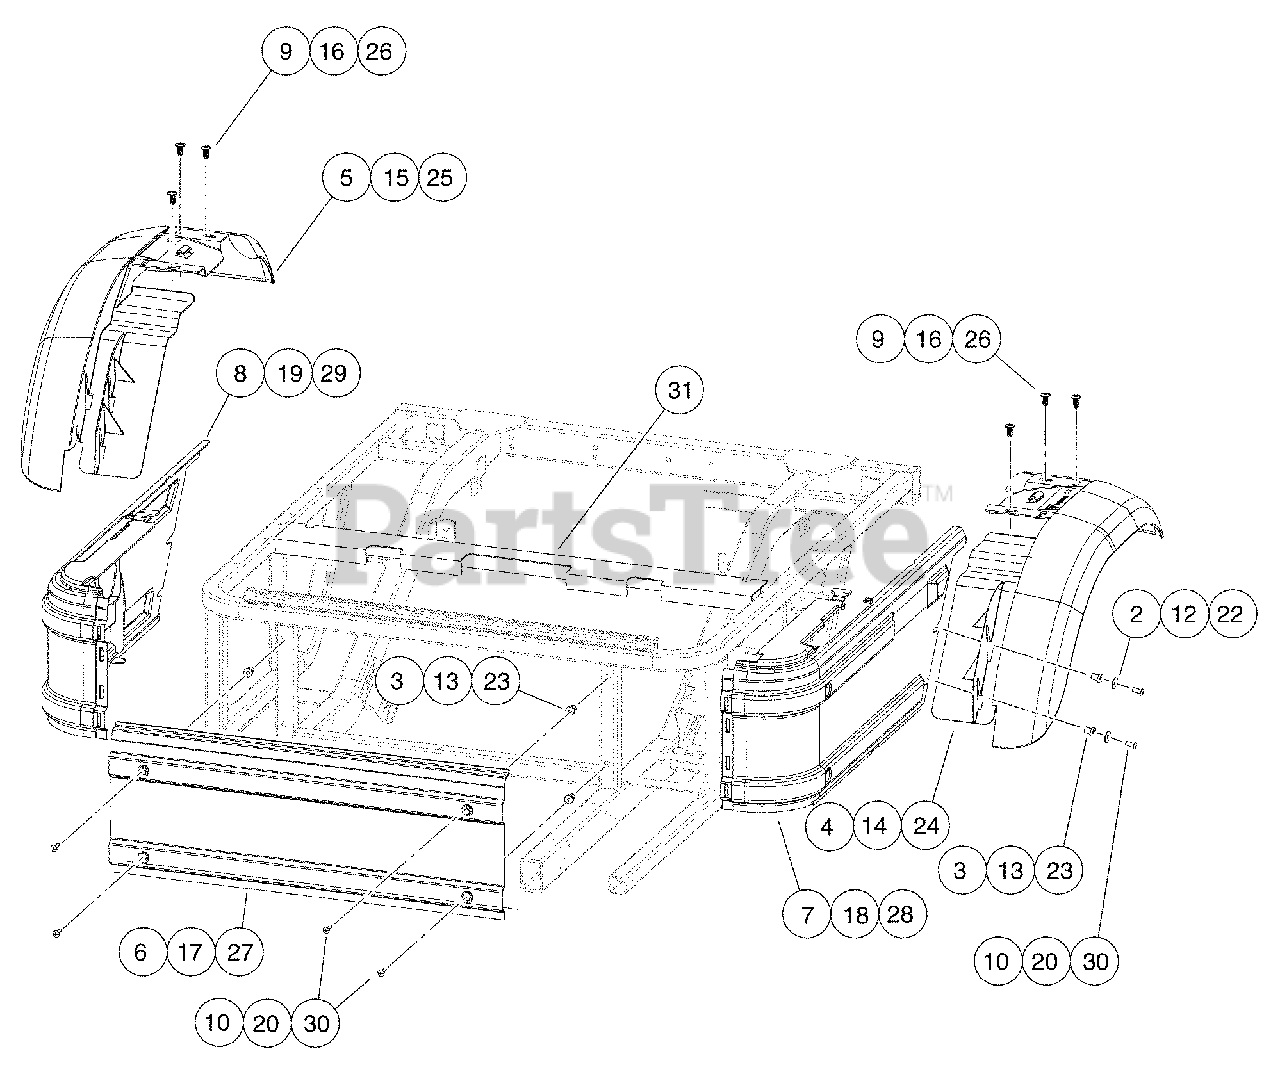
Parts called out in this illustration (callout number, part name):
1	Instl, Panels, Fenders, Blk
2	Washer, 1/4" Type B Flat
3	Well Nut 1/4-20
4	Left Rear Fender
5	Right Rear Fender
6	Panel, Front, Kick
7	Panel, Side, Molded, Driver
8	Panel, Side, Molded, Passenger
9	Screw, Tuflok, 10mm
10	Screw, 1/4-20 X 1.0 Truss-Head Machine
11	Instl, Panels, Fenders, Rthwd
12	Washer, 1/4" Type B Flat
13	Well Nut 1/4-20
14	Left Rear Fender
15	Right Rear Fender
16	Screw, Tuflok, 10mm
17	Panel, Front, Kick, Rthwhd
18	Pnl, Side, Mld, Drv, Rthwhd
19	Pnl, Side, Mld, Pass, Rthwhd
20	Screw, 1/4-20 X 1.0 Truss-Head Machine
21	Instl, Panels, Fenders, Moff
22	Washer, 1/4" Type B Flat
23	Well Nut 1/4-20
24	Left Rear Fender
25	Right Rear Fender
26	Screw, Tuflok, 10mm
27	Panel, Front, Kick, Moff
28	Pnl, Side, Mld, Drv, Moff
29	Pnl, Side, Mld, Pass, Moff
30	Screw, 1/4-20 X 1.0 Truss-Head Machine
31	Closeout, Extrusion
